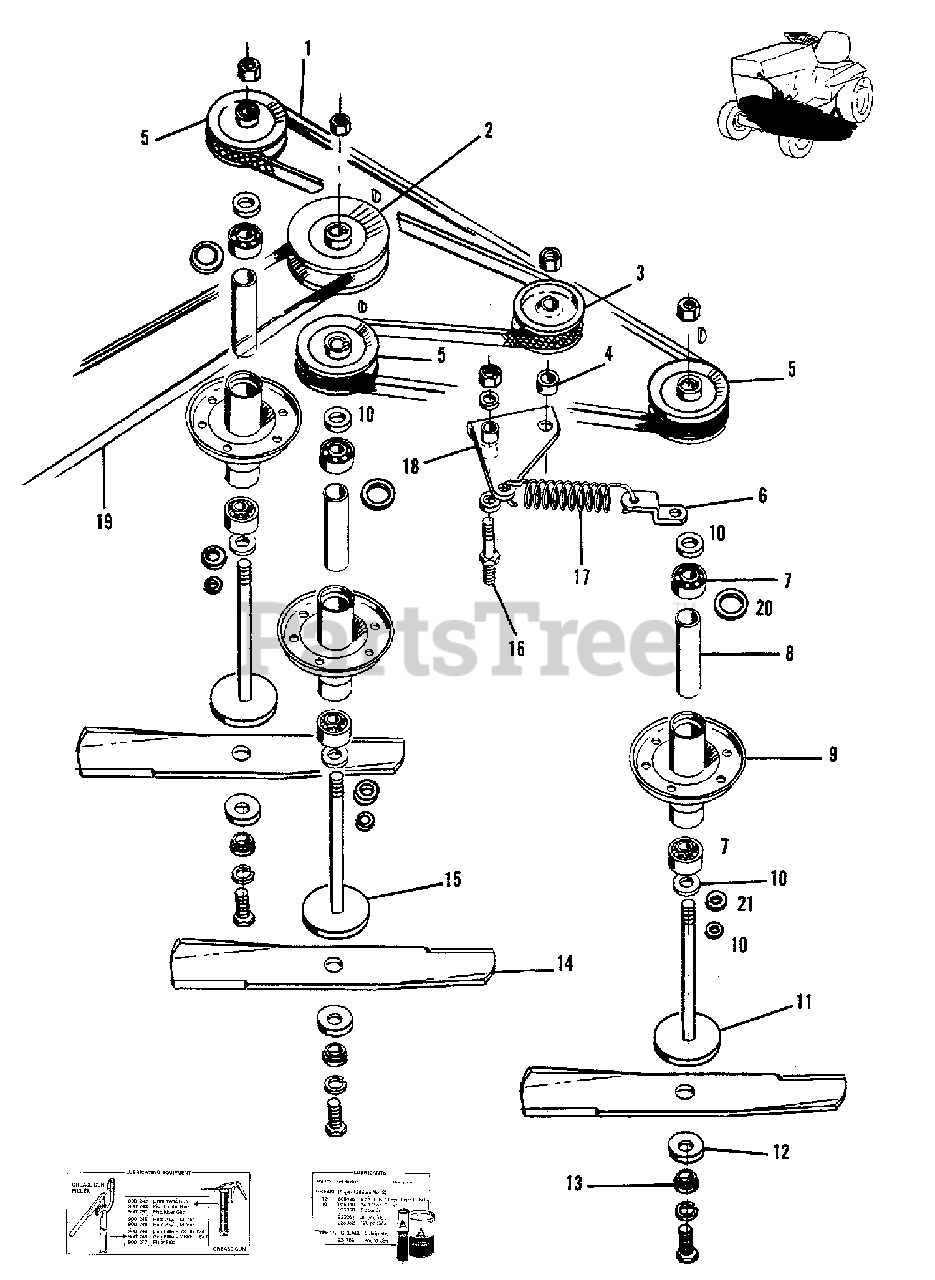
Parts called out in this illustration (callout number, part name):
1	V-BELT, Arbor Drive (42" Mower)
1	V-BELT, Arbor Drive (48" Mower)
2	SHEAVE, Top Center (42" Mower)
2	SHEAVE, Top Center (48" Mower)
3	PULLEY, Idler
3	CAPSCREW, 3/8NC x 1-3/4
3	WASHER, Plain, 13/32 x 7/8 x #14
3	LOCKWASHER, 3/8
3	NUT, 3/8NC
4	SPACER, Pulley & Lever
5	SHEAVE, Center & Outer
5	WASHER, Plain, 25/32 x 1-1/4 x #7 (Between Sheaves On Center Arbor)
5	KEY, Woodruff, 3/16 x 5/8
6	CLIP, Spring Anchor
7	BEARING, Ball
8	SPACER, Tube Assembly
9	TUBE ASSEMBLY, Arbor (Includes Item 7,8 & 20)
9	CAPSCREW, 5/16NC x 3/4
9	WASHER, Plain, 3/8 x 7/8 x #16
9	LOCKWASHER, 5/16
9	NUT, 5/16NC
10	WASHER, Special .754 x 1.25 x .015
11	SHAFT ASSEMBLY, Arbor, Left & Right
11	NUT, Lock, Jam, 3/4NF
12	WASHER, Spring
13	WASHER, Shouldered
13	CAPSCREW, 7/16NF X 1-1/2, Grade 8
13	LOCKWASHER, 7/16
14	BLADE, Knife (42" Mower)
14	BLADE, Knife (48" Mower)
15	ARBOR ASSEMBLY, Center
15	NUT, Lock, JAM, 3/4NF
16	STUD, Idler
16	WASHER, 3/8
16	LOCKWASHER, 3/8
16	NUT, 3/8NC
16	NUT, Lock, 3/8NC
16	WASHER, Plain, 13/32 x 7/8 x #14
17	SPRING, Lever
18	LEVER ASSEMBLY, Idler
19	V-BELT, PTO, Front (42" Mower)
19	V-BELT, PTO, Front (48" Mower)
20	RING, Bearing Back-Up
21	WASHER, Special
